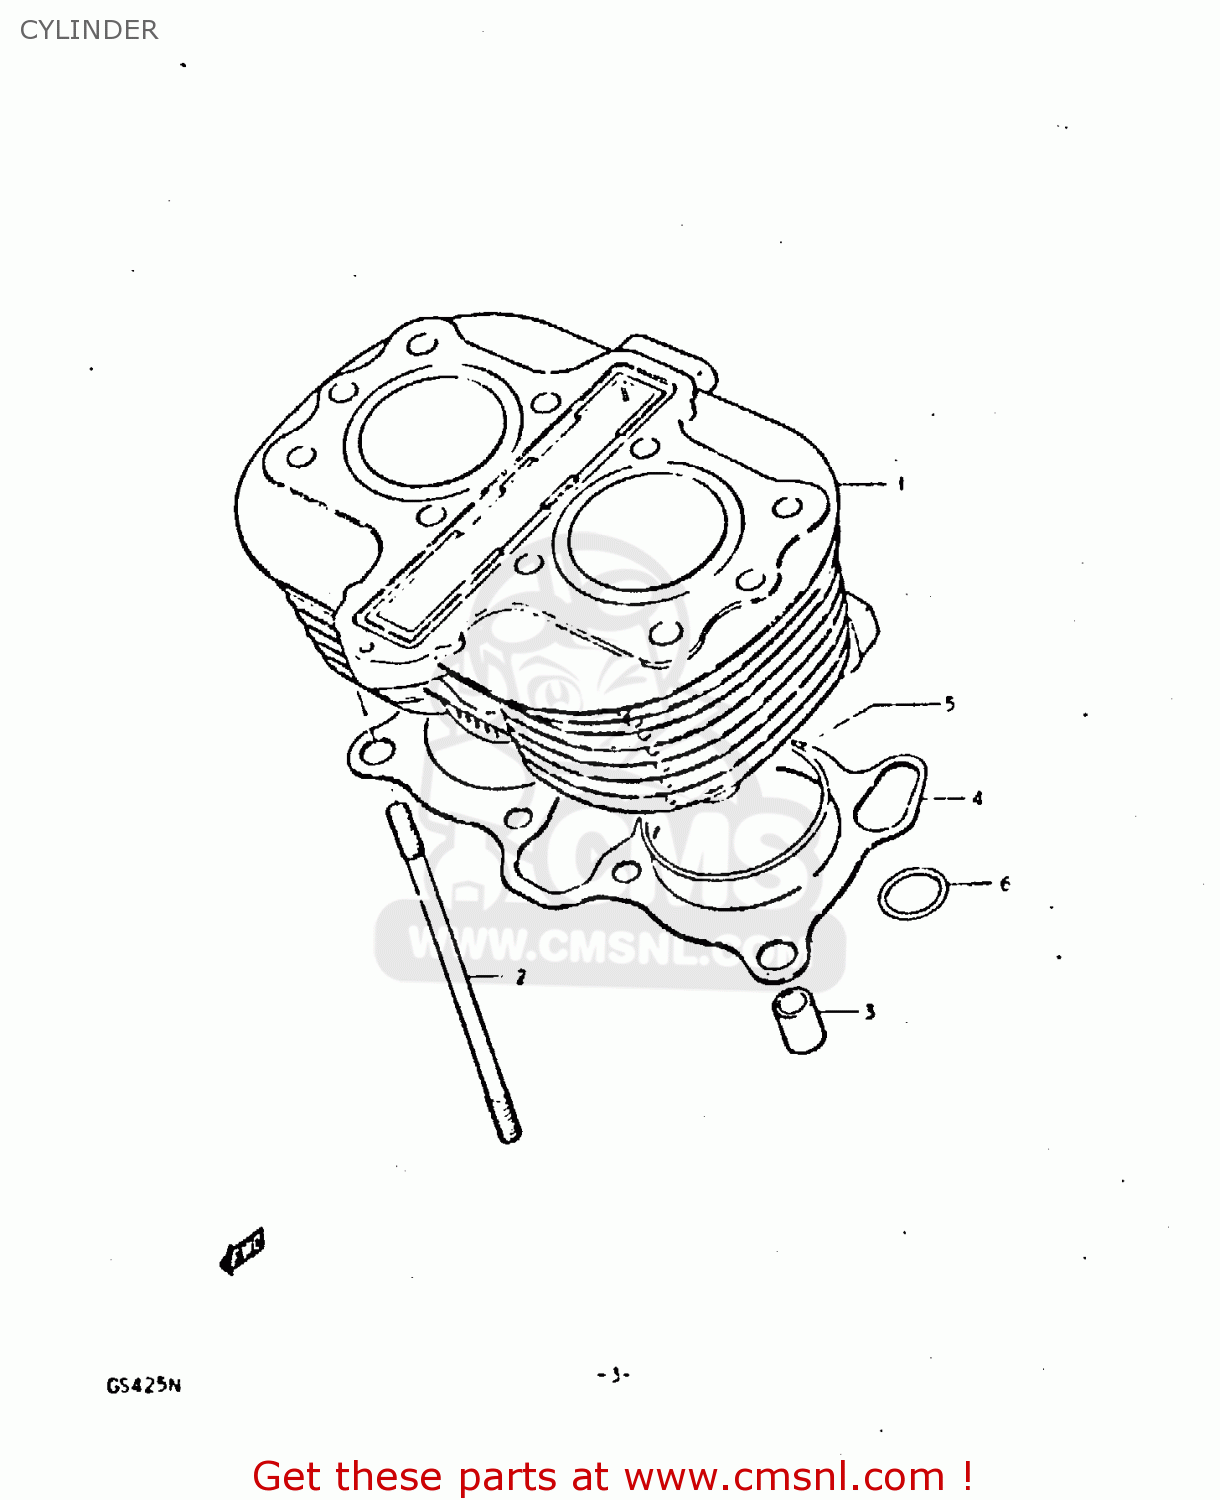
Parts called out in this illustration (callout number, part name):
1	CYLINDER
2	STUD
3	PIN
4	GASKET,CYLINDER (MCA)
5	O RING(D:2,ID:70)
6	O RING(D:3.05)
